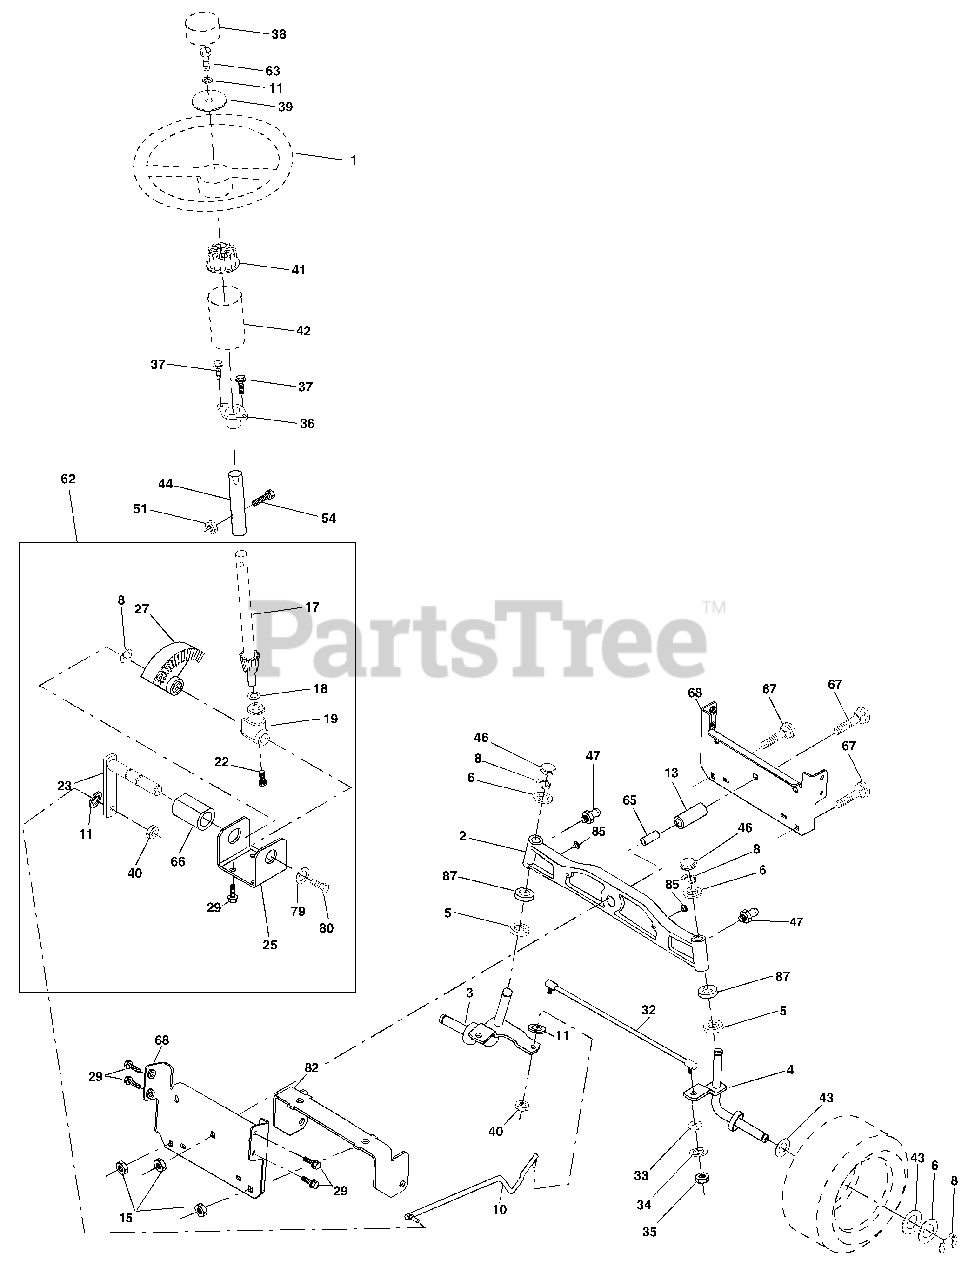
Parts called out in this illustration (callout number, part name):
1	Wheel Steering
2	Axle Asm Cast Iron LT
3	Spindle Asm LH
4	Spindle Asm RH
5	Bearing Race Thrust Harden
6	Washer 25/32 X 1-5/8 X 16 Ga
8	Ring Klip #t5304-75
10	Link Drag
11	Washer Lock Hvy Hlcl Spr 3/8
13	Spacer Brg Axle Front
15	Nut Hex Flange Lock
17	Shaft Asm Strg
18	Washer Thrust 515 x 750 x 033
19	Support Shaft
22	Screw Hex Wsh Hd Torx
23	Shaft Asm Pittman
25	Bracket Steering
27	Gear Sector
29	Screw 3/8-16 x .75
32	Rod Tie
33	Washer 11/32 x 3/4 x 16 Ga
34	Washer Lock Hvy Hlcl Spr 5/16
35	Crownlock Nut 5/16-24 Unf
36	Bushing Strg
37	Screw
38	Insert Cap Strg Wh
39	Washer 13/32 X 1-1/20 X 11 Ga
40	Lock nut
41	Adaptor Wheel Strg
42	Boot Steering Dash
43	Washer 25/32 X 1 1/4 X 16 Ga
44	Extension Steering Shaft LR/LT
46	Cap Spindle Fr Top Blk
47	Fitting Grease
51	Nut Lock Hex w/Ins 5/16-18
54	Bolt Fin Hex 5/16-18 Unc x 1-1/4
62	Kit, Steering Assembly Svc
63	Bolt Fin Hex 3/8-16unc x 1 Gr. 5
65	Spacer Brace Axle
66	Bearing Arm Pittman
67	Bolt Rdhd Sq 3/8-16 Unc x 2-3/4
68	Axle, Brace
79	Washer 13/32 x 1-1/4 x 12 Ga.
80	Bolt Hex Nylon 3/8-16 x 3/4
82	Bracket Susp Chassis Front
85	Fastner Christmas Tree
87	Washer Flat .781 x 1-1/2 x .14
